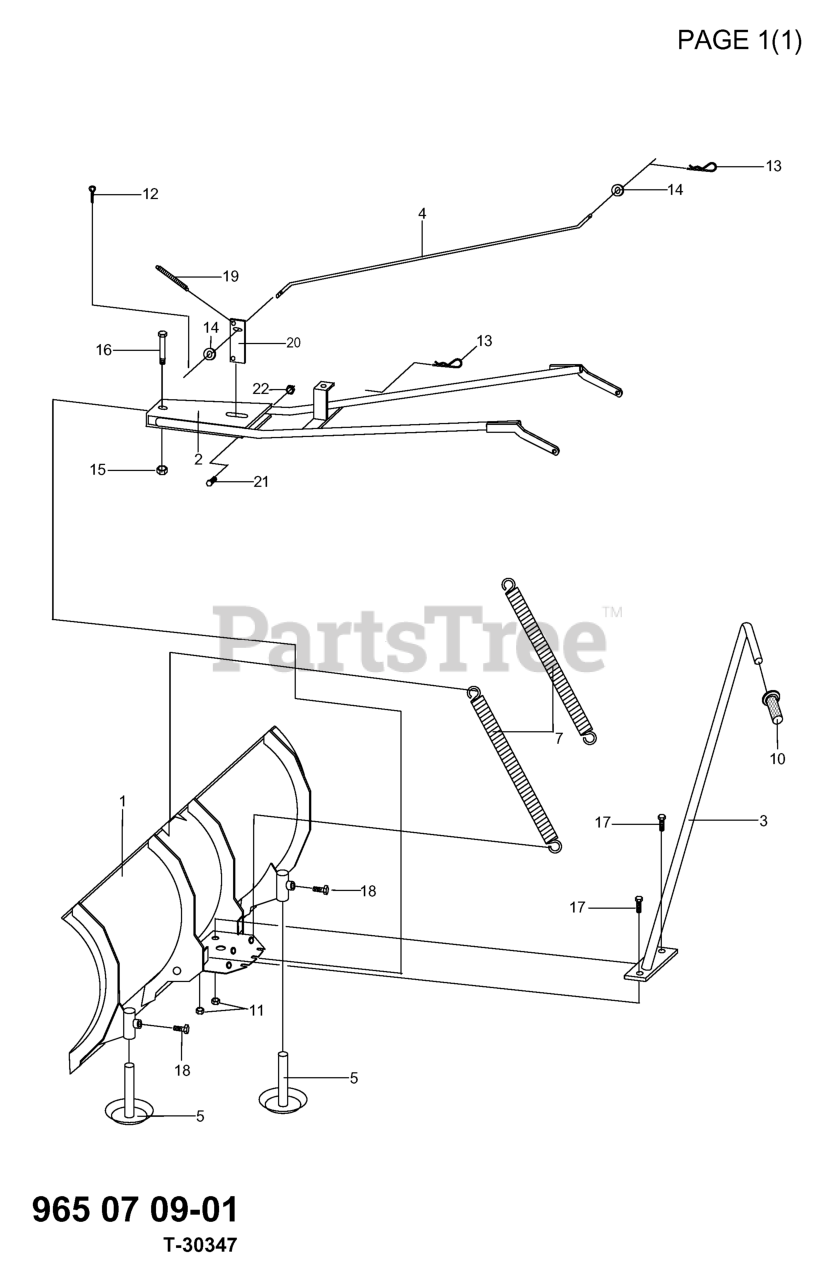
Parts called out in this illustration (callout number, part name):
3	Angle Control Tube
5	SLIDING SHOE
20	Plate, Lock
